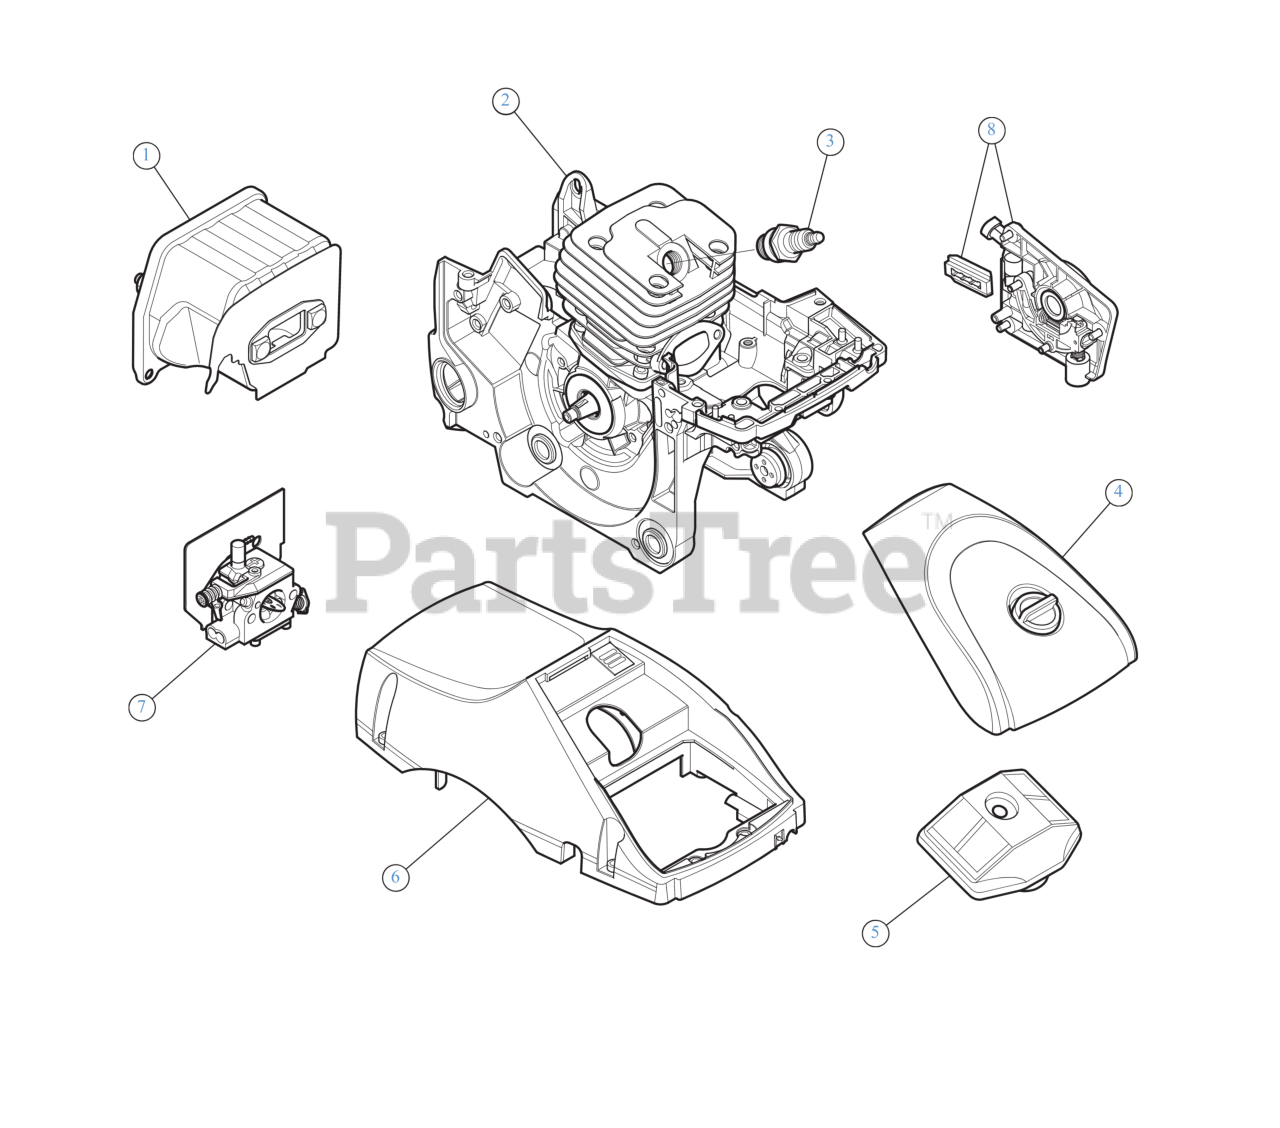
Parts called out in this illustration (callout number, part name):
1	MUFFLER ASSEMBLY
2	SHORTBLOCK 46CC
3	SPARK PLUG:L8RTF YD4500-26200
4	AIR FILTER COVER ASSEMBLY
5	AIR FILTER W/SEAL
6	COVER
7	CARBURATOR
8	PUMP ASM:OIL
